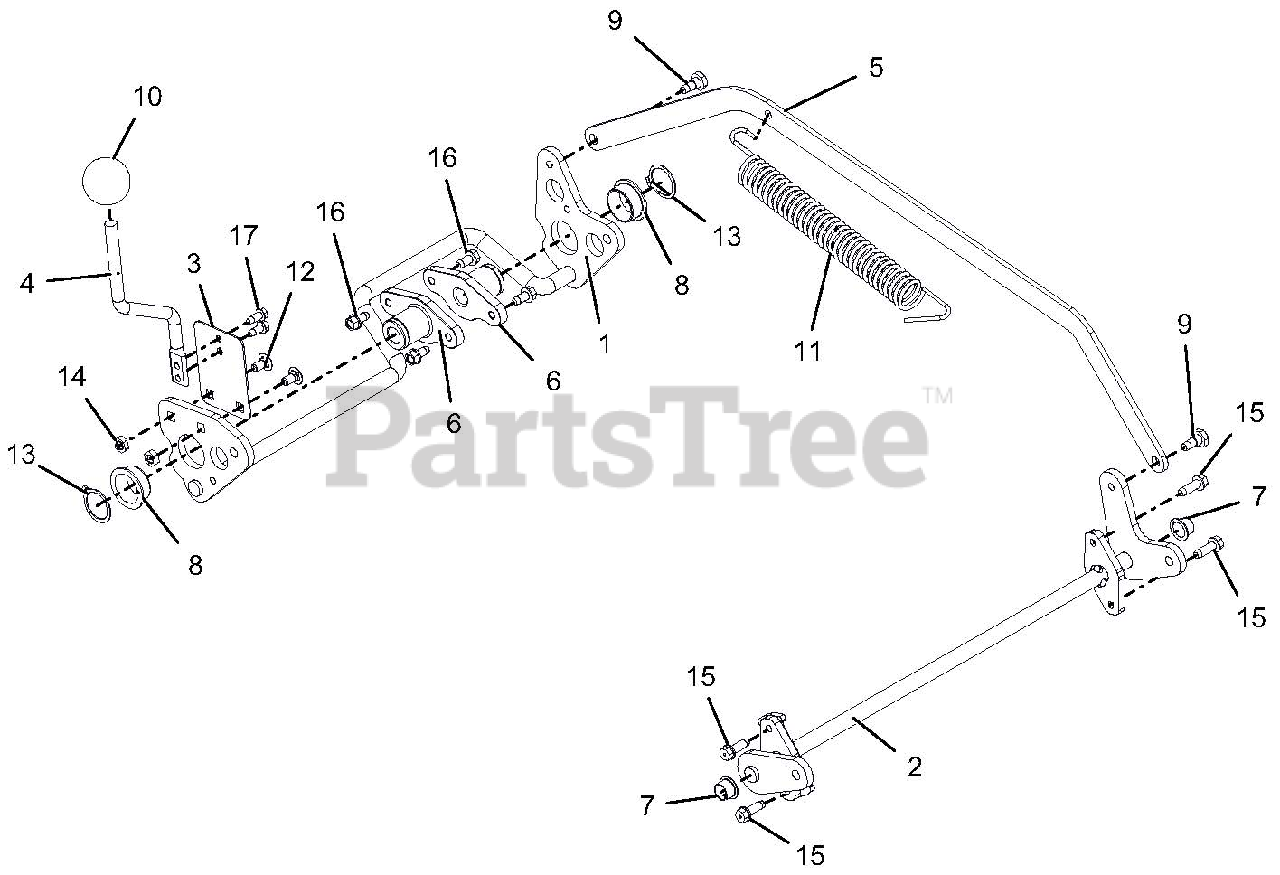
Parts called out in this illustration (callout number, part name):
1	WLDMT, REAR AXLE
2	WMT, LM FRONT AXLE
3	PLATE, HOC SPRING
4	LEVER, HOC ADJUSTMENT
5	LINKAGE, HOC CONNECT
6	HUB, LM REAR AXLE
7	BUSHING, POLYLINER-.50 SPLIT
8	BSHG-FLG 1.0X1.125X.50X1.375 R
9	BOLT, SHLDR .320X.210X.25-20
10	KNOB,BALL -BLACK 1.47" .375-16
11	SG-TENS .121X1.00X6.5 WLD
12	@BLT-RDHDSQNK .25-20X.50 G5YZ
13	RG-RTNG-EXT 1.00X.042
14	NUT-LK-CTR JAM .25-20 YWZC
15	SCR-TAP-PM .25-20X.75 TR YWZ
16	SCR-TAP .25-20X.50 HWH TR YWZ
17	@SCR-TAP 12-24X.50 HWH TR YWZC
